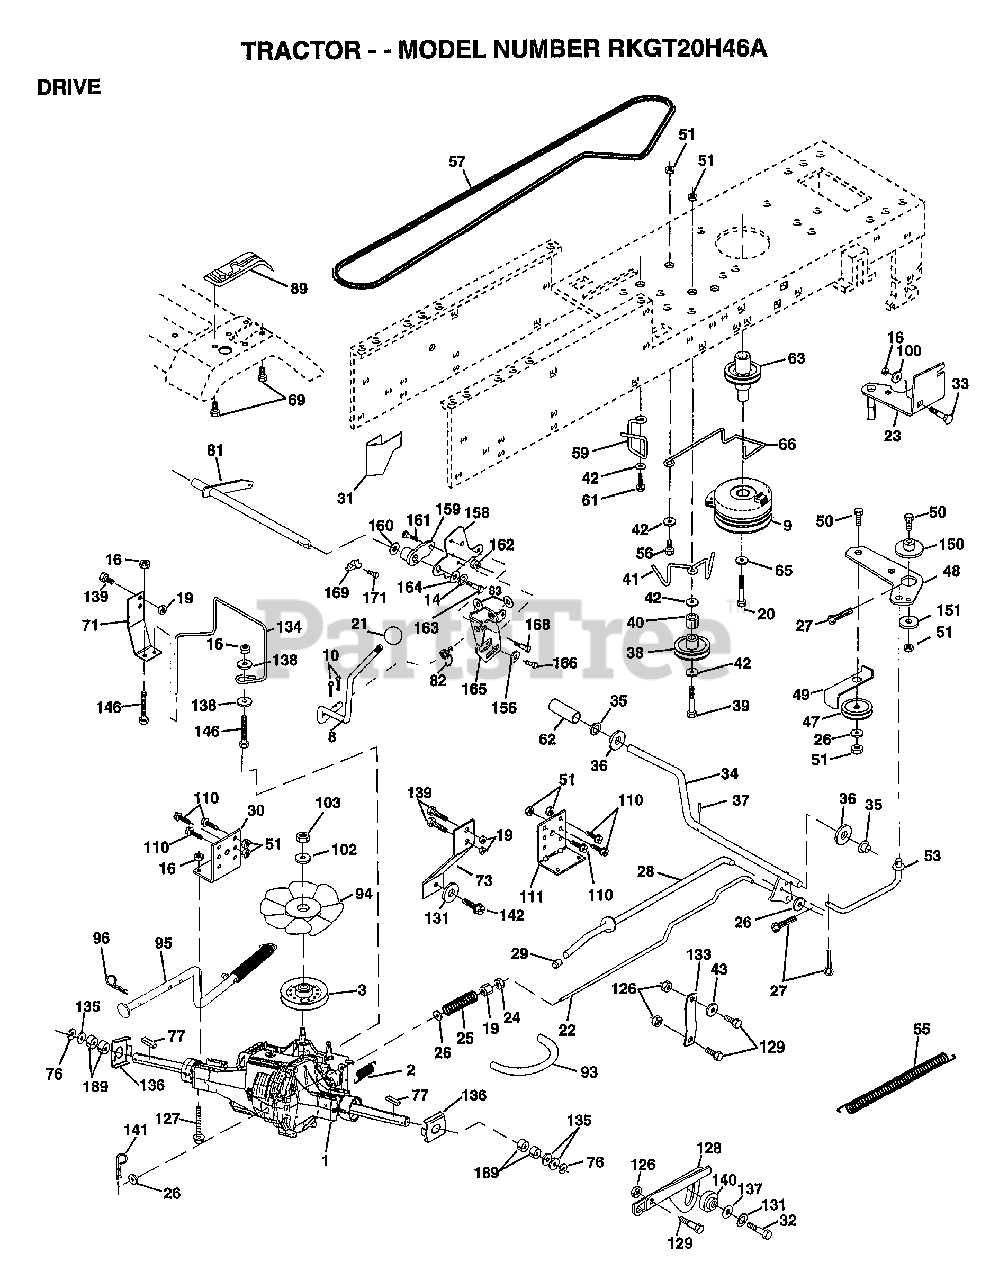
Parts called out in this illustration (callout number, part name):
2	SPRING RET BRAKE
3	PULLEY.TRANSAXLE
8	ROD.SHIFT.FEND.ADJ.YT
9	CLUTCH.ELECTRIC
10	PIN COTTER 1/8
14	LOCKWASHER
16	NUT
19	NUT
20	BOLT.7/16-20X4.25
21	KNOB.DUCKHEAD.1/2
22	BRAKE.ROD.HYDRO.
23	BRACKET.CLUT.MTG.
24	NUT
25	SPRING ROD LT
26	WASHER
27	COTTER PIN
28	ROD.BRAKE.PARK.LT
29	PLUNGER CAP T
30	BRKT TRANS LH
31	KEEPER BELT LH
32	BOLT
33	BOLT
34	SHAFT ASM-PEDAL F
35	NYLON BEARING
36	WASHER LT
38	FLAT IDLER PULLEY
39	BOLT
40	SPACER T
41	"KEEPER,BELT.IDLER FLAT"
42	WASHER
43	WASHER T
48	BELLCRANK.CLUTCH
49	RETAIN BELT
53	"LINK, CLUTCH T"
55	"SPRING, RETURN LT"
57	BELT.DRIVE
59	KEEPER BELT CNTSP
61	SCREW
62	"COVER,PEDAL"
63	PULLEY.ENGINE
65	LOCKWASHER
66	ENGINE BELT KEEPR
69	SCREW HEXWSH H-L
71	STRAP.TORQUE.LH.HYDRO
73	STRAP.TORQUE.RH.HYDRO
76	E RING HYT
77	SQ KEY STD
81	SHIFT.ASM.CROSS.TAPER
82	"SPRING,TORSION"
83	WASHER
89	CONSOLE.SHIFT.AUTO.YT/GT.BLACK
93	"LINE FUEL HYD 4"""
94	"FAN 7"" HYDRO"
95	CONTROL.ASM.BYPAS
96	RETAINER M
100	WASHER M
102	WASHER BELLEVILLE
111	BRKT TRANS RH
127	BOLT.HEX.FLGHD.
128	BRKT NEUTRAL ADJ
133	TRANSAXLE LINK
134	"KEEPER BELT,RH"
135	WASHER
136	WASHER.AXLE.HYDRO
137	WASHER
138	WASHER
139	BOLT
140	BUSHING.PINION.SECTOR
142	BOLT.5/16X24X1
145	BOLT.HEX.FLGHD
146	BOLT.HEX.FLGHD.
150	BUSHING.BELLCRANK.GRD.DR
151	WASHER
156	WASHER.SRRTD.5/16
158	BRKT.SHIFT.MOUNT
159	HUB.SHIFT
160	WASHER
161	BOLT T
164	WASHER.5/8X.281X10GA
165	BRKT.PIVOT.LEVER
166	SCREW.5/16-18X5/8
168	BOLT.SHOULDER.5/16-18X.561
169	PLATE.FASTENING
171	SCREW LT
189	WASHER.SPACER AXL
